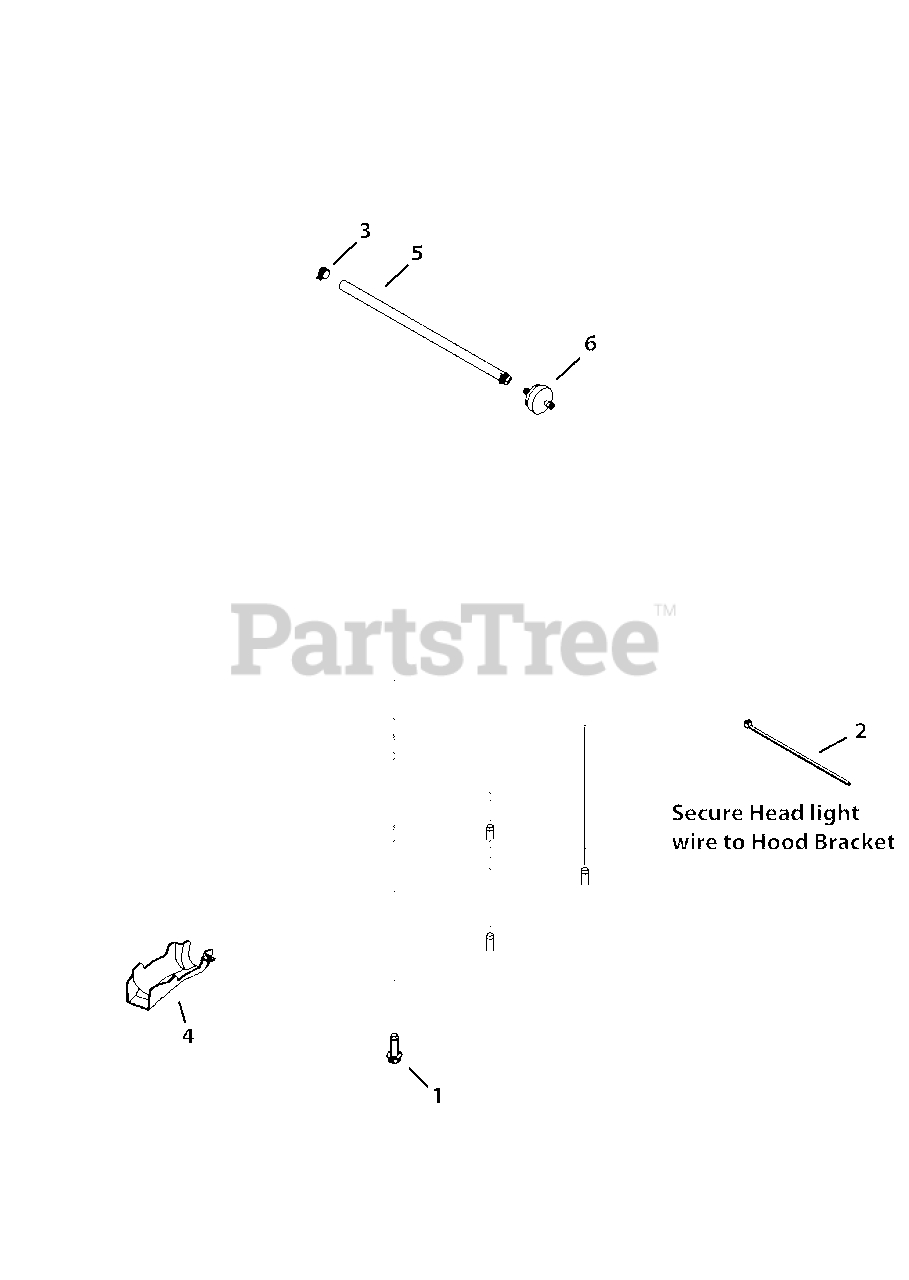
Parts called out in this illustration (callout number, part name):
1	Screw, 3/8-16 x 1.0
2	Cable Tie
3	Clamp Hose, .490 diameter
4	Oil Drain Sleeve
5	Fuel Hose, Low Permeation
6	Fuel Filter
